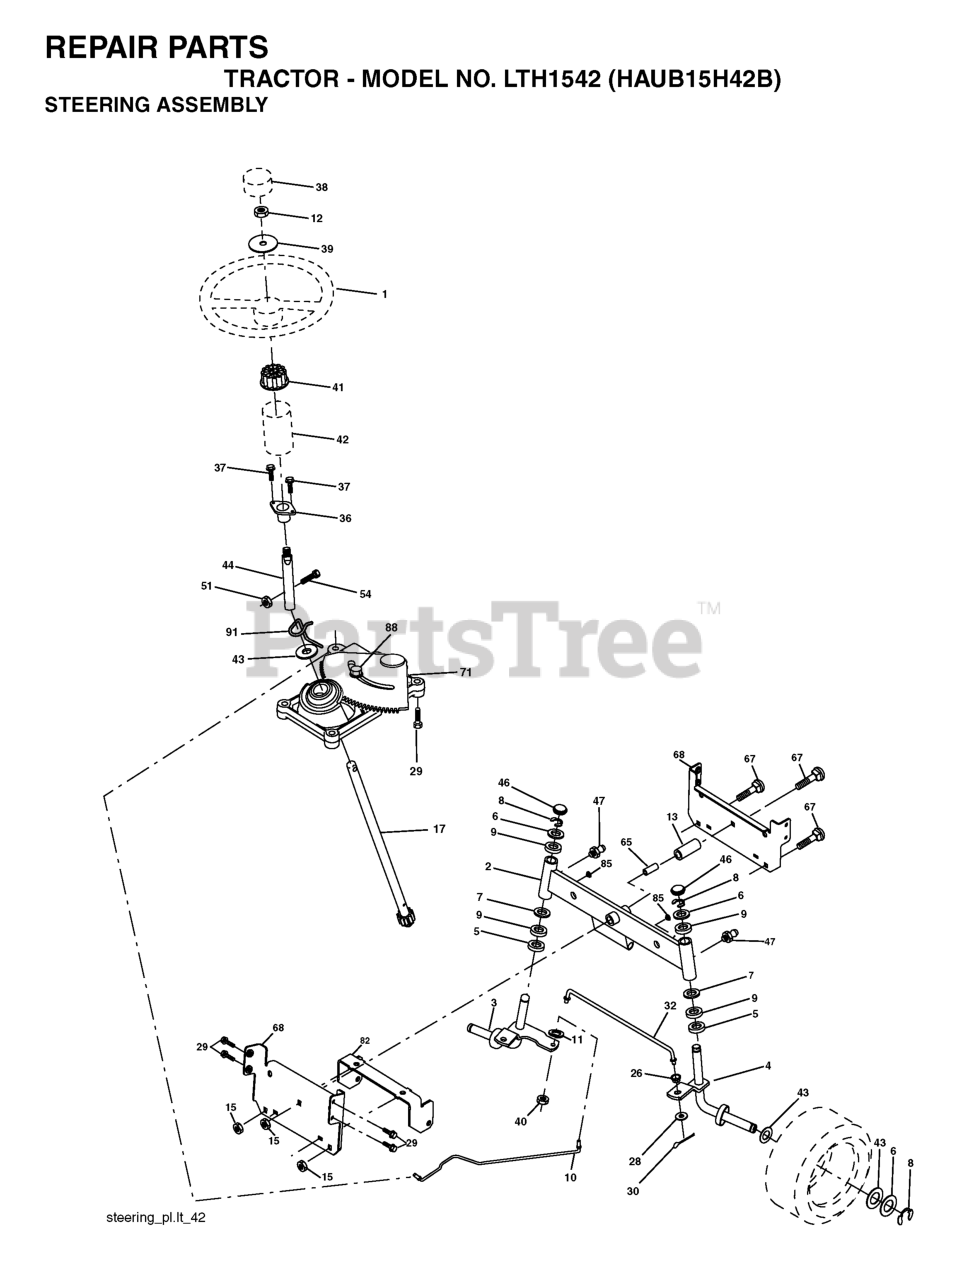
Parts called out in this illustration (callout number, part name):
1	STEERING WHEEL
2	AXLE ASM.
3	SPINDLE.ASM.LH.15"TIRES
4	SPINDLE.ASM.RH.15"TIRES
5	THRUST WASHER
9	BRNG T
10	DRAGLINK.15".TIRES.2001
11	WASHER, LOCK 3/8
12	NUT.HEX.1/2-20
13	TUBE, PIVOT AXLE
15	NUT
17	SHAFT ASM, STEERING
26	BUSHING.DRAGLINK (2 2)
28	WASHER
29	SCREW 3/8-16X3/4
30	COTTER PIN
32	TIE ROD
36	BUSHING, STEERING
37	SCREW.TT.#10-32X.5.3/8.FLANGE
38	CAP.WHEEL.STEERING.GREY
39	Washer 9/16 ID x 1 1/2 OD 11 Ga. Zin
40	GRIPCO NUT
41	STEERING WHEEL ADAPTOR
42	BOOT STEERING
44	EXT, STEERING SHAFT
46	CAP, AXLE BLK
47	FITTING.GREASE.TAPERED
51	NUT.CROWNLOCK.1/4-28
54	Bolt Hex 1/4-28 unf x 1-1/4 Gr. 8
65	SPACER BRACE AXLE
67	BOLT CARRIAGE
68	BRACE.AXLE.15"TIRES
71	STEERING ASM
82	BRACKET
85	FASTENER.XMAS.TREE
88	BOLT, SHOULDER 7/16-20
91	CLIP.STEERING
